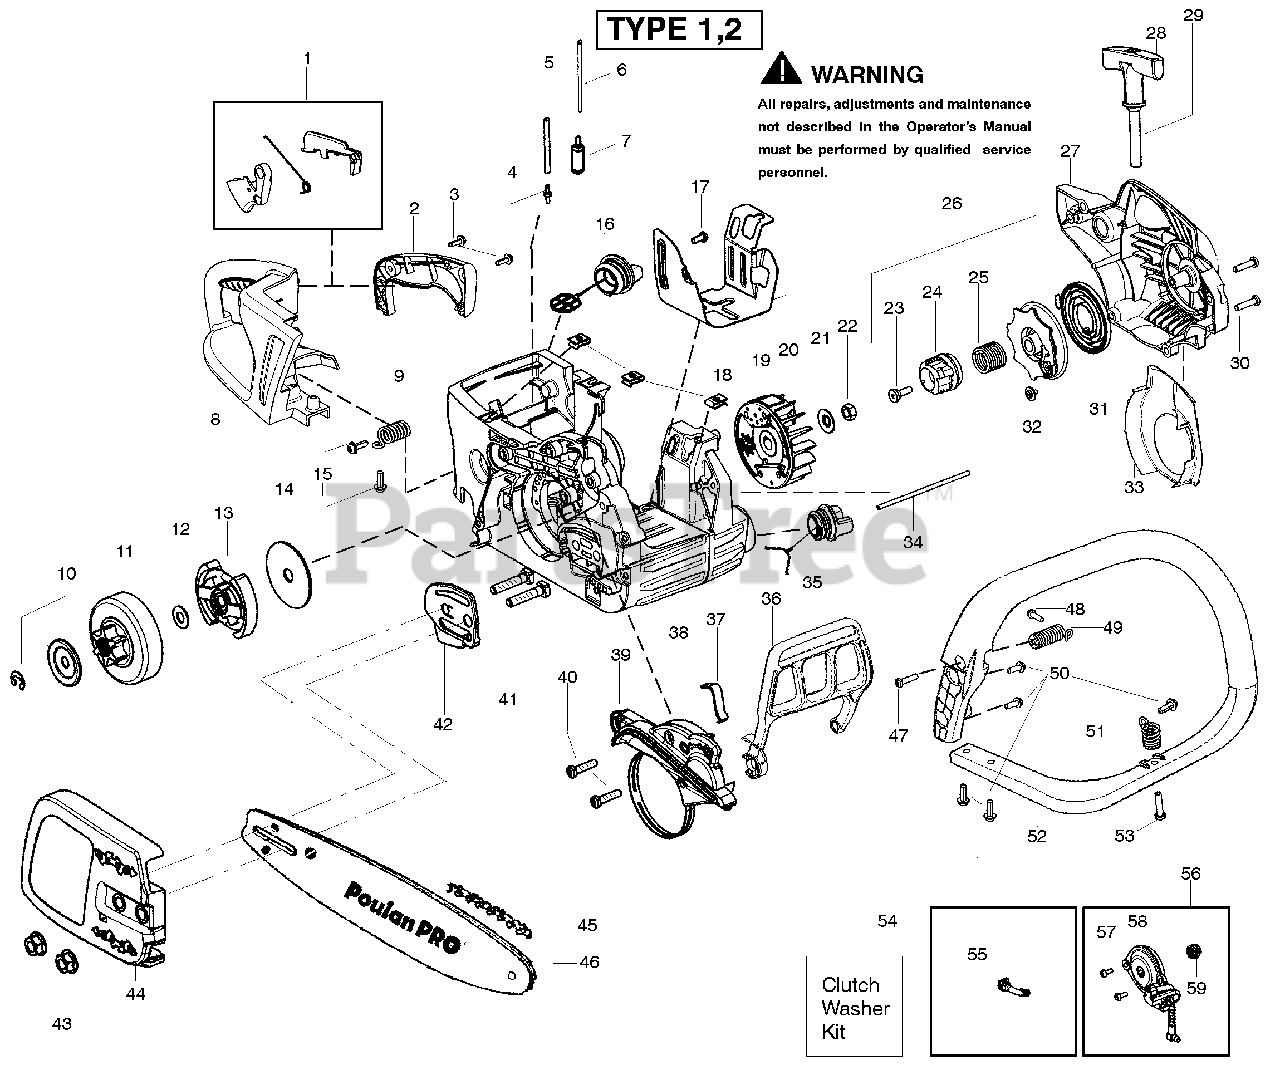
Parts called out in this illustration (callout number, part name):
1	Kit-Trigger/Lockout
2	Cover-Handle
4	Fitting-Fuel line
5	Kit-Fuel Line (Large)
6	Kit-Fuel Line (Small)
7	Assy-Fuel Pick Up
8	Handle-Rear
9	Spring-Rear Isolator
10	Kit-Clutch Washer
11	Assy-Clutch Drum 3/8"
12	Kit-Clutch Washer
13	Assy-Clutch
14	Washer-Large Clutch
16	Assy-Fuel Cap w/ret
18	Nut-"U" type speed
19	Assy-Flywheel
20	Shield-Heat
21	Washer-Flywheel
22	Nut-Flywheel
23	Screw-Shoulder
24	Starter Hub-EPS
25	Spring-EPS
26	Kit- EPS Starter Pulley
27	Housing-Fan
28	Handle-Starter
29	Kit-Rope
31	Spring-Starter
34	Assy-Oil Vent
35	Assy-Oil Cap w/ret.
36	Handguard
37	Spring-Handguard
38	Assy-Chassis
39	Kit-Chainbrake
41	Bolt-Bar
42	Plate-Bar
44	Assy-Clutch Cover
45	Accy-16" Chain
46	Accy-16" Bar
49	Assy-Rear Iso. Spring
51	Assy-Front Iso. Spring
52	Handle-Front
54	Kit-Clutch Washer
55	Assy-Oil Pick Up
56	Kit-Oil Pump
57	Screw
58	Assy-Oil Pump
59	Gear-Worm
